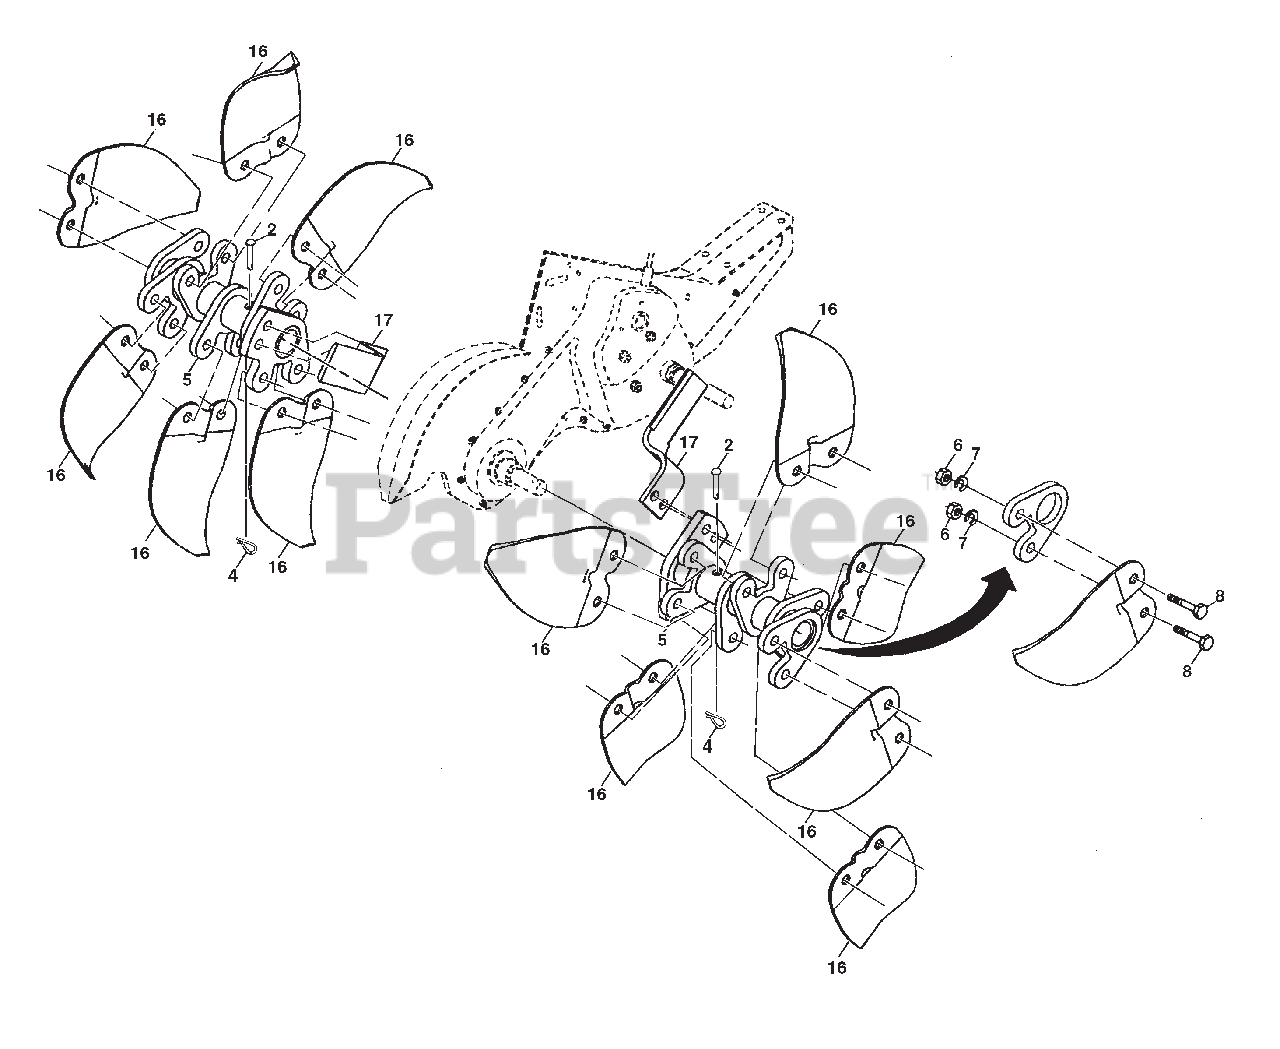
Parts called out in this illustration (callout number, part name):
2	Pin, Shear
4	Retainer, Spring
5	Tine Assembly
6	Nut, Hex 3/8-24
7	Washer, Lock 3/8
8	Bolt, Hex 3/8-24 x 1
16	Tine, Spade
17	Tine, Cleaning
